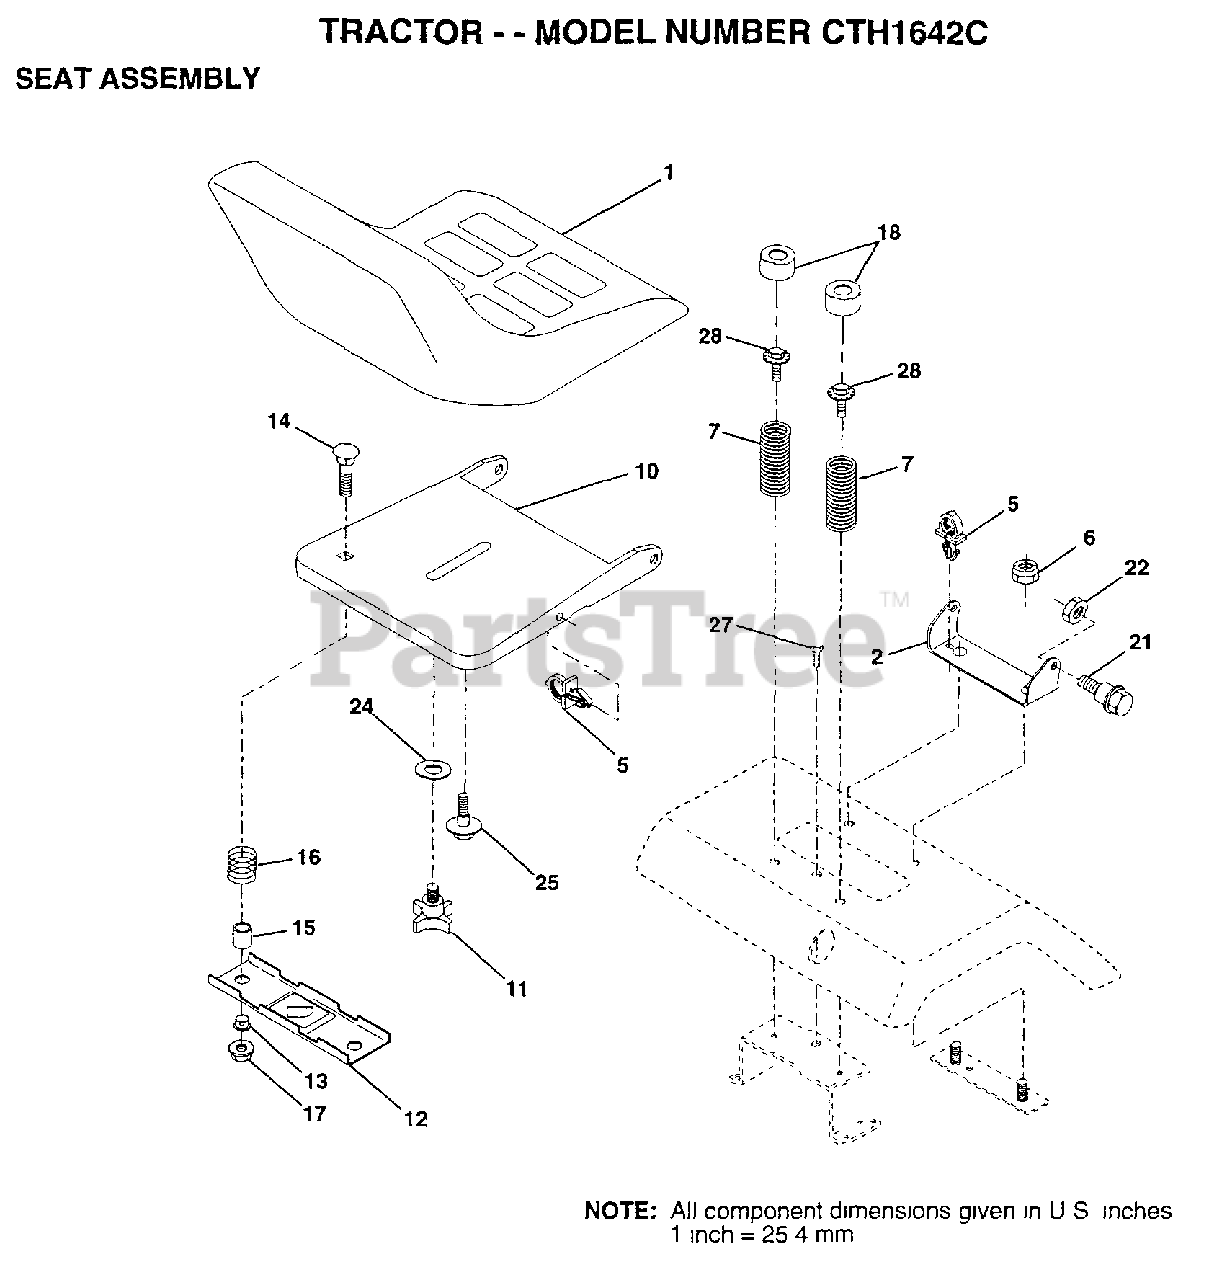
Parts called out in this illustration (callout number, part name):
2	BRACKET PVT SEAT
5	CLIP.PUSH-IN.HING
6	NUT
7	SPRING COMPRESSIO
8	SCREW LT
9	WASHER
11	"KNOB 1/2"" YT"
12	BRKT SWITCH
13	BUSHING
15	SPACER SPLIT
16	SPRING COMPRESSED
18	CAP SPRING
21	"BOLT,SHOULDER"
24	WASHER
25	"BOLT,SHOULDER"
27	SCREW LT
28	BOLT.5/16-18.UNC
